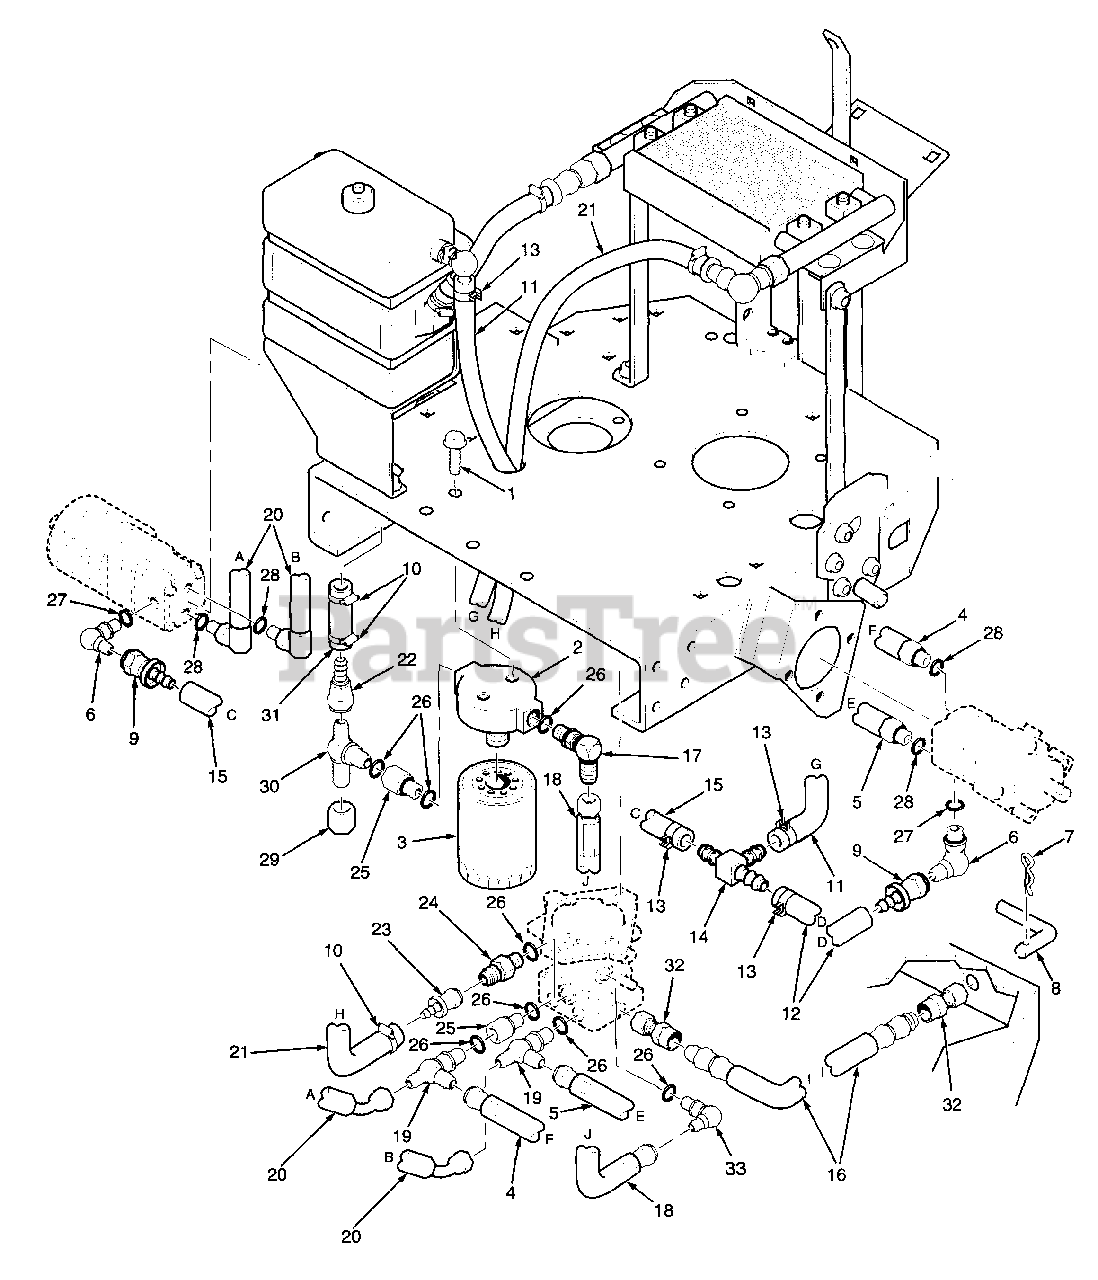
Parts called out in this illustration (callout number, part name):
1	Capscrew, 1/4-20 x 1/2 Serr. Fl. Hex Head
2	Filter Head
3	Filter, Spin-On Lube
4	Hose Assembly
5	Hose Assembly
6	Elbow, 90 Degrees
7	Hairpin Cotter
8	Lever, Dump Valve
9	Connector, Flare Swivel with Hose Barb
10	Hose Clamp
11	Hose, 1/4 Pushlock
12	Hose, 1/4 Pushlock
13	Hose Clamp
14	Tee Union, Pushlock Hose
15	Hose, 1/4 Pushlock
16	Hose, Dump Valve
17	Elbow, 90 Deg.
18	Inlet Hose, 3/4" ID
19	Tee, 1/2" Run
20	Motor Hose
21	Hose, Pump To Oil Cooler
22	Coupling, Flare Swivel
23	Coupling, Flare Swivel With Barb
24	Tube Union
25	O-Ring Bushing
26	O-Ring
27	O-Ring
28	O-Ring
30	Tee, Jic to O-Ring
31	Hose, Order by the inch
32	Compression Fitting
33	Elbow, 90 Deg.
